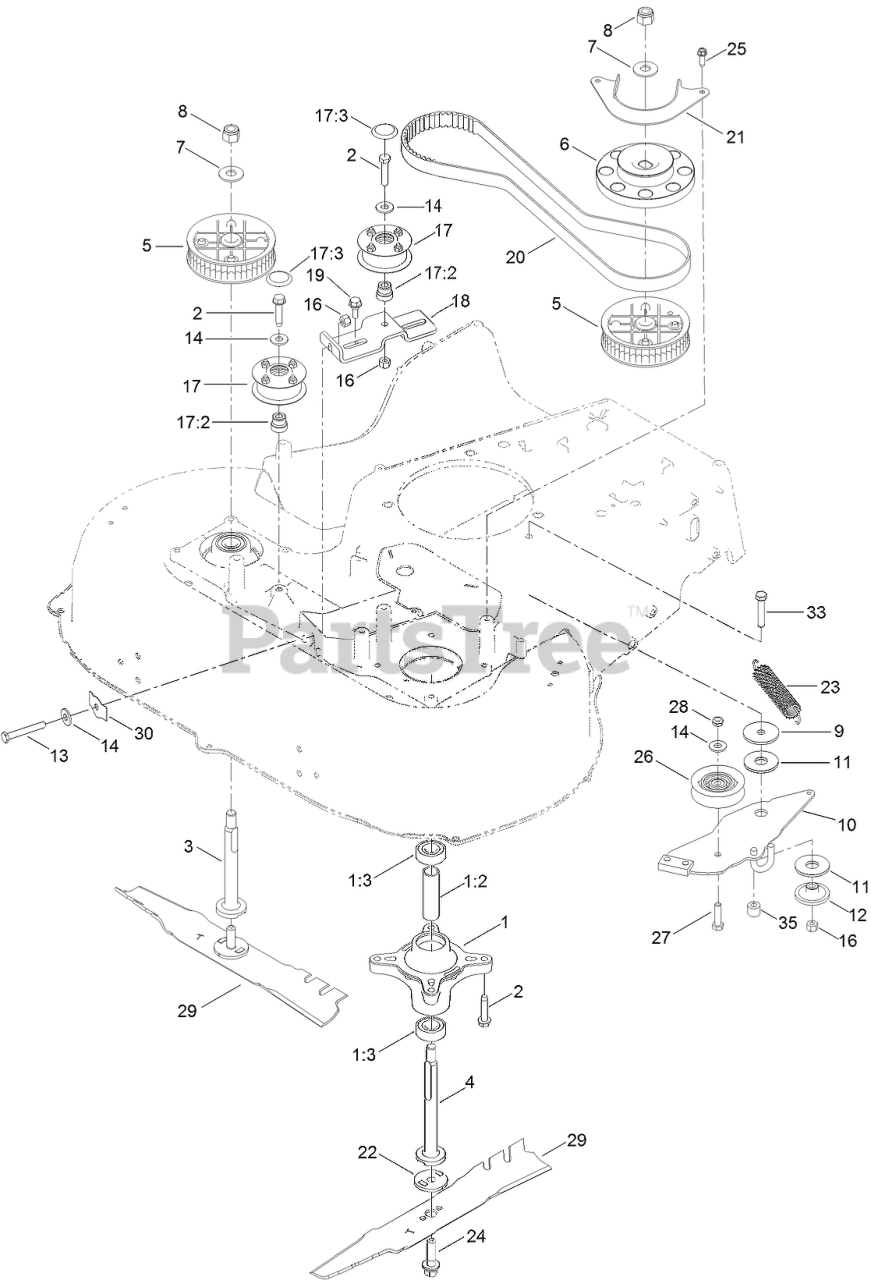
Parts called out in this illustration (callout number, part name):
1	SPINDLE ASM
1:2	SPACER
1:3	BEARING-BALL
2	SCREW-HWH
3	SHAFT-SPINDLE
4	SHAFT-SPINDLE
5	SPROCKET
6	PULLEY-BRAKE, SPINDLE
7	WASHER-SPRING
8	NUT-HEX
9	WASHER-REBOUND
10	BRAKE ARM ASM
11	WASHER-FRICTION, COMPOSITE
12	SPACER
13	BOLT-TAP, HH
14	WASHER-FLAT
16	NUT-LOCK, NI
17	PULLEY KIT
17:2	ADAPTER-BORE
17:3	PLUG-CAP
18	BRACKET-IDLER
19	SCREW-SHOULDER,HWH
20	BELT-SYNCHRONOUS
21	GUIDE-BELT, SPINDLE
22	ADAPTER-BLADE
23	SPRING-EXTENSION, BRAKE
24	BOLT-BLADE
25	SCREW-HWHTF
26	PULLEY-IDLER
27	SCREW-HH
28	NUT-LOCK, NI
29	BLADE-ROTARY
30	SPRING-FLAT
33	SCREW-HH
35	HOSE-COOLANT
